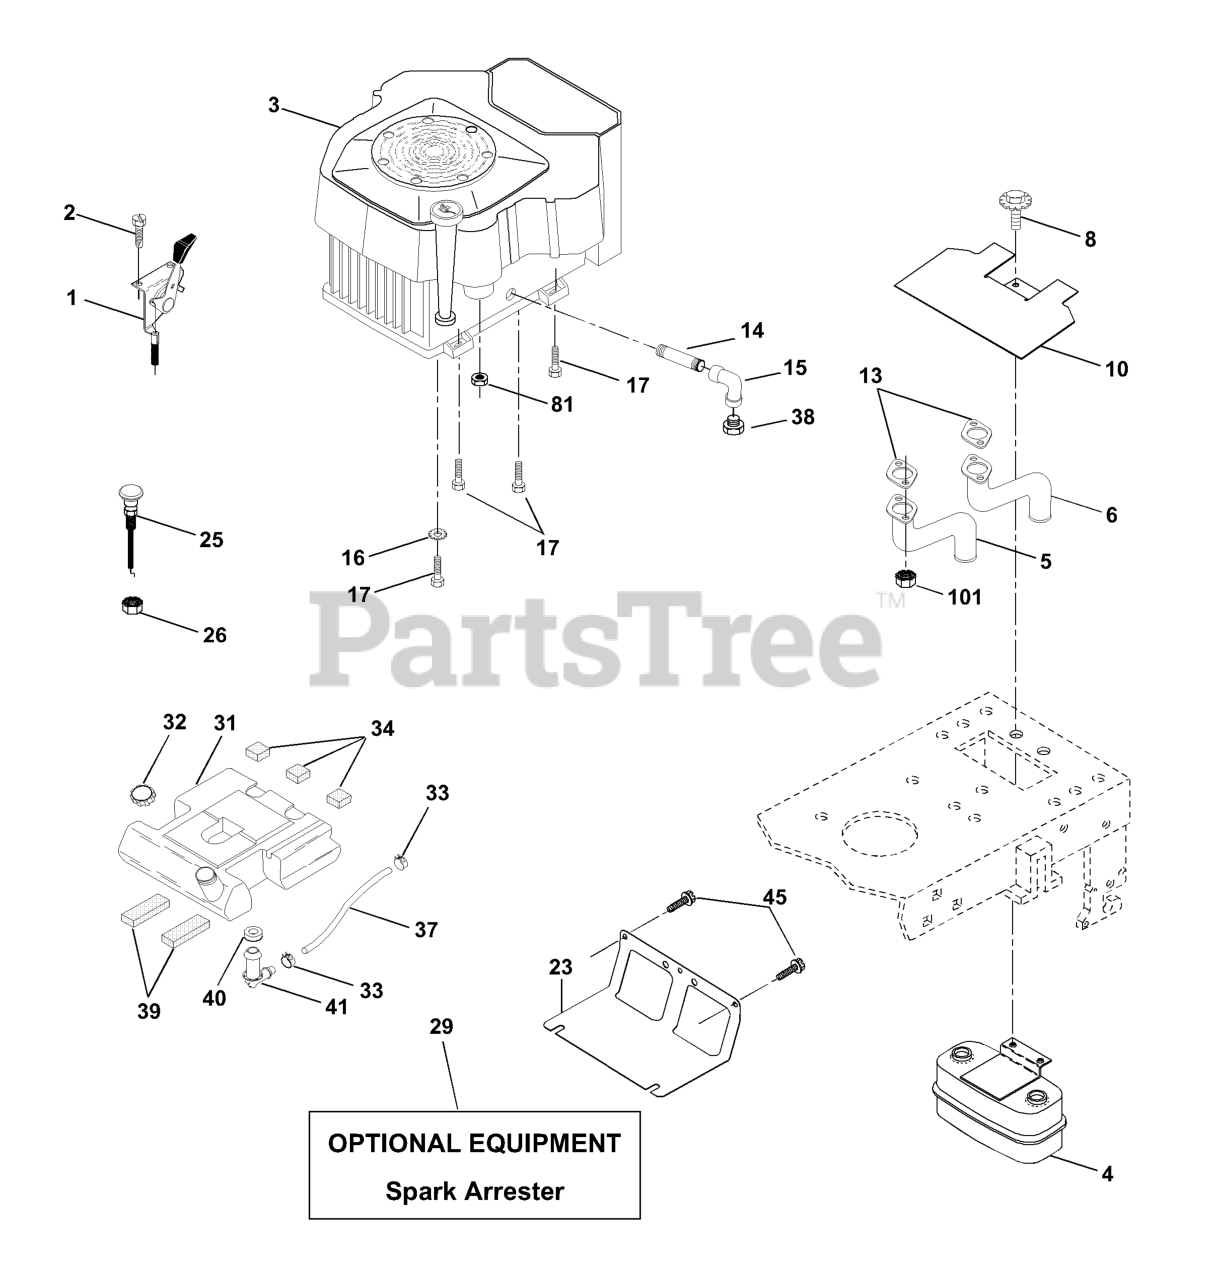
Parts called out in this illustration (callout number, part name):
1	CONTROL THROTTLE
2	SCREW LT
4	MUFFLER.TWIN.CYL.LOW.TONE
5	RP.PIPE-EXHAUST LH
6	RP.PIPE-EXHAUST RH
8	BOLT HEX WASHER HD 5/16-18
10	RP SHIELD HEAT MUFFLER
13	GASKET.KOHLER
14	Nipple, Pipe 3/8 NPT x 4-1/2
15	ELBOW
16	LOCKWASHER
17	SCREW LT
23	SHIELD.BROWNING.DBR.GUARD
25	CONTROL, CHOKE
26	Nut, Keps 3/8-24 UNF
29	KIT.SPARK ARRESTOR 794945 B&S
31	FUEL TANK 3.5G
32	FUEL CAP
33	HOSE CLAMP
34	PAD-SPACER LT
37	REPL BY 532 00 85-43
38	Plug, Oil Drain
39	PAD IDLER TI
40	BUSHING OUTLET T
41	STEM FUEL TANK
45	SCREW, 3/8-16X3/4
81	NUT
101	FLANGE NUT
